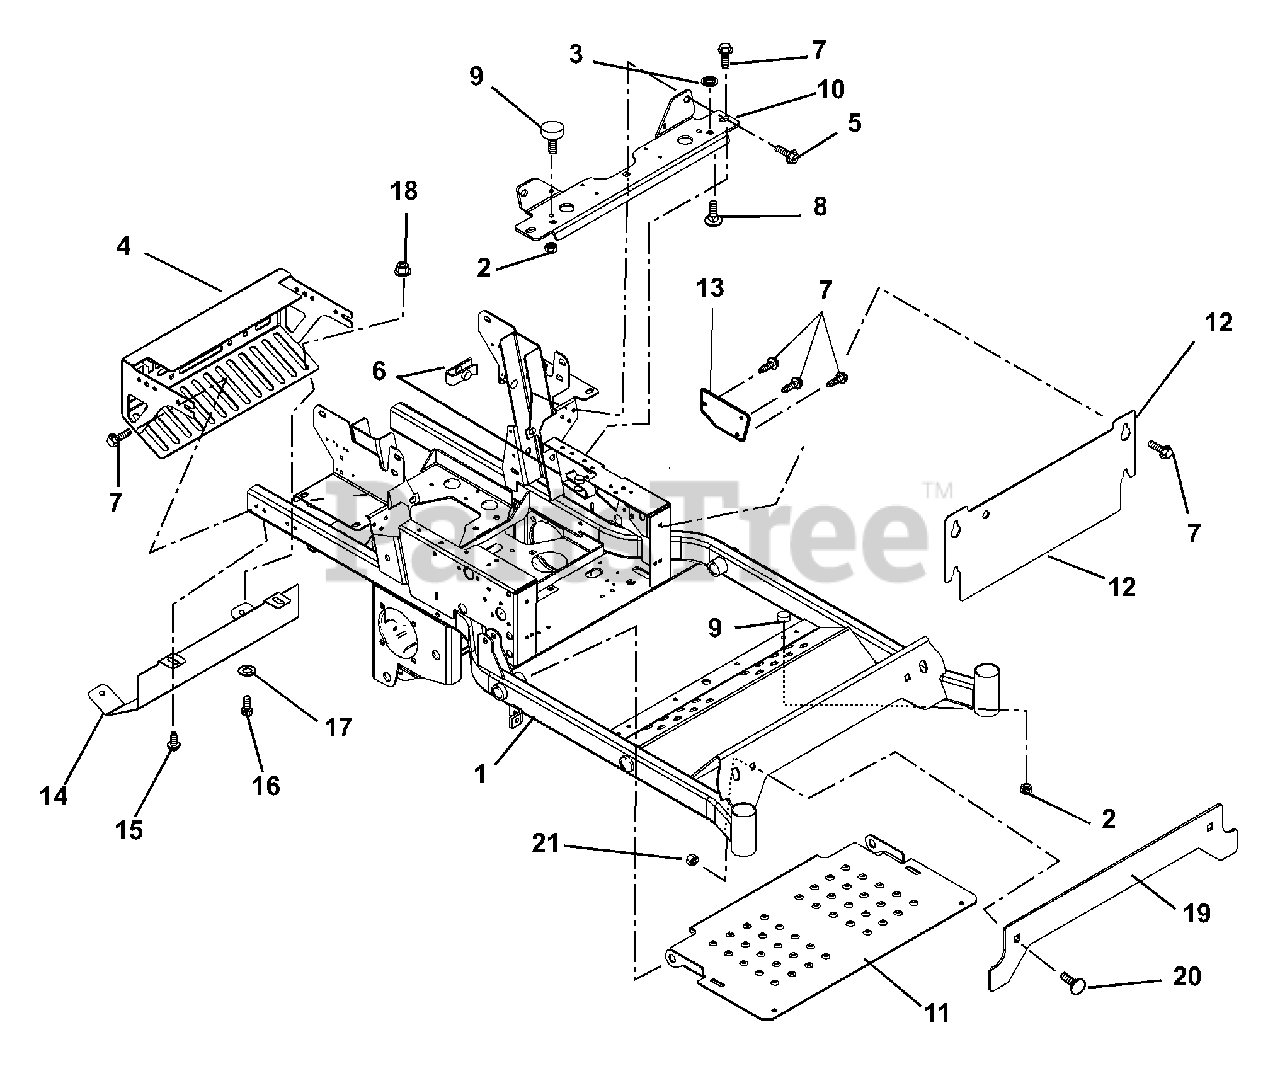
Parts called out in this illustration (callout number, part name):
1	Intermediate-Z Frame
2	Nut, Spin Lock Flange .312-18
3	Nut, Push .312
4	Bumper, IZ with Standard air cleaner
5	Bolt, Serrated Flange Washer Head .38-16 x 1.00
6	Nut, Retainer .375-16 x .37
7	Screw, Tapping Hex Washer Head .38-16 x .50
8	Bolt, Round Head Square Neck .31-18 x 1.00 Grade 5
9	Bumper, Rubber
10	Seat Support
11	Footrest Panel
12	Access Panel
13	Valve Cover
14	Heat Shield
15	Screw-Tapping .38-16 x .50 Hex Washer Head Thread Rolling YWZ
16	Bolt-Hex .38-16 x .75 Grade 5
17	Washer-Flat-Steel .438 x 1.00 x .083
18	Nut-Locking-Top-Flange .38-16
19	Plate, Counterweight
20	Bolt-Round Head Square Neck .50-13 x 1.75 Grade 5
21	Nut .50-13 Nyloc Flange
